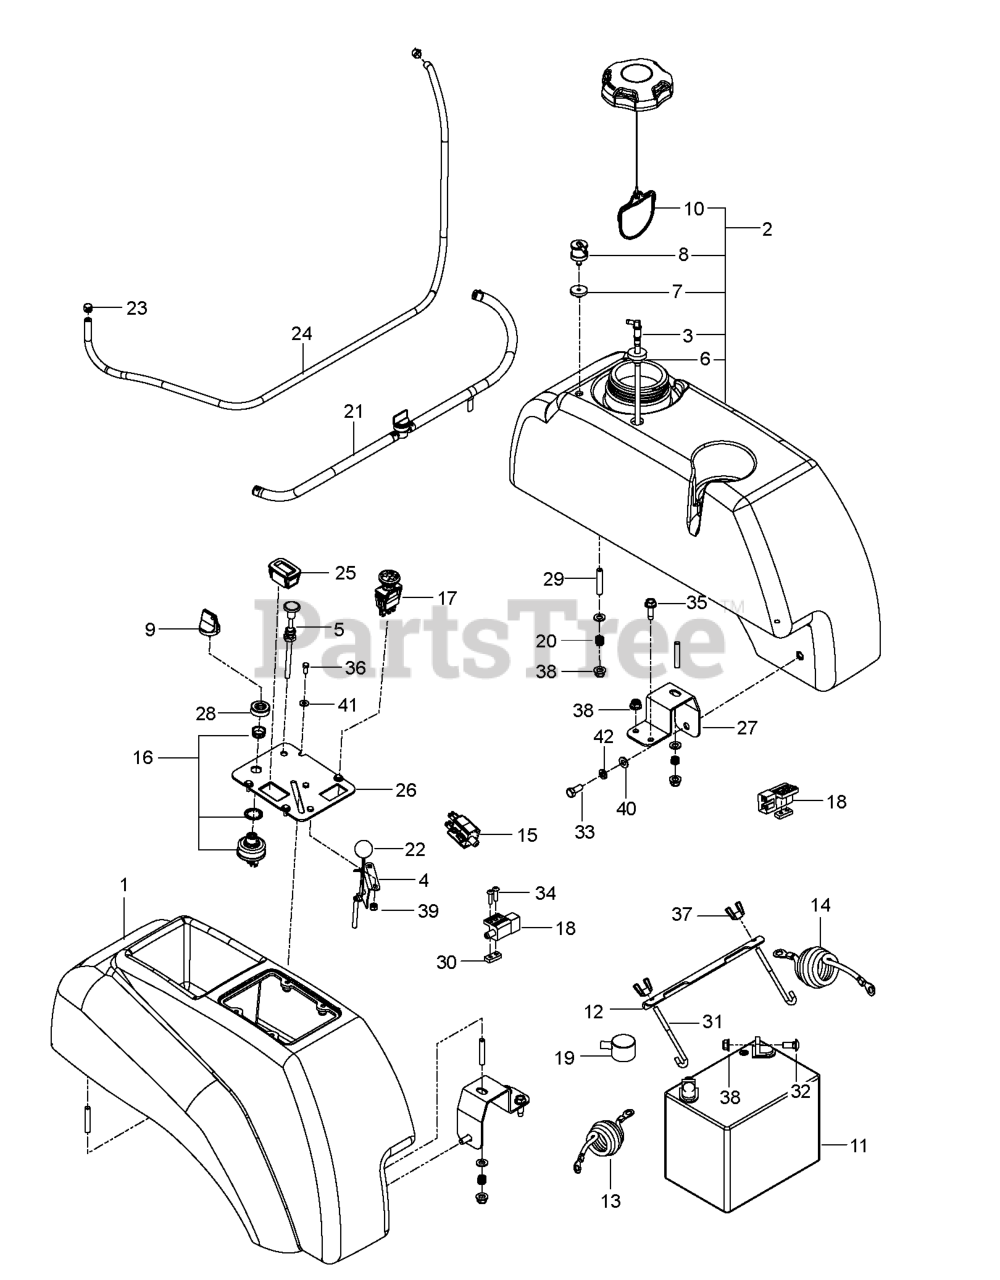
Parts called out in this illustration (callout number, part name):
1	FENDER CONSOLE
2	FUEL.TANK.ASSY.LH.MZ.GRY
3	FITTING, FUEL
4	THROTTLE CABLE
5	CABLE, CHOKE, 38
6	RUBBER GROMMET
7	GROMMET, CHECK VALVE
8	VALVE.FUEL.CHECK
9	KEY, IGNITION
10	CAP, FUEL
11	BATTERY, 12 V 330 AMP
12	BRACKET.BATTERY.MOUNT.PLATED
13	CABLE.BATT.SOLENOID.MZ.RED.25"
14	CABLE.GROUND.BATT.MZ.BLACK.39"
15	SWITCH.INTRLCK.CLUTCH.
16	SWITCH, IGNITION, INDAK
17	RP SWITCH.PTO.TERMINAL.STD.RED
18	SWITCH INTERLOCKT
19	COVER.TERMINAL.BATTERY
21	FUEL.HOSE.SHUT.OFF.ASM.10".10"
22	KNOB.ROUND.BALL.BLACK
23	CLAMP, HOSE
24	HOSE.3/16".VAPOR.LINE.36"LGTH
25	GUAGE.SRVCMNDR.HRMTR.
26	PLATE, CONSOLE, BLK
27	SUPPORT, TANK, BLK
28	CAP IGNITION NUT
29	STUD, 5/16C
30	PLATE NUT ZTR
31	HOOK, "J"
32	RP BOLT 5/16-18 X3/4 ZN/YEL GR
33	BOLT.FIN.HEX.5/16-18X3/4
34	SCR #10-24 X .75 SKT HD BLK
35	HCS #10-24 X 1/2
36	SCREW
37	WING NUT 1/4
38	5/16-18 NYLOC FLANGE NUT
39	NUT 10-24 NYLOC
40	WASHER
42	WASH.5/16.SLW.ZD
